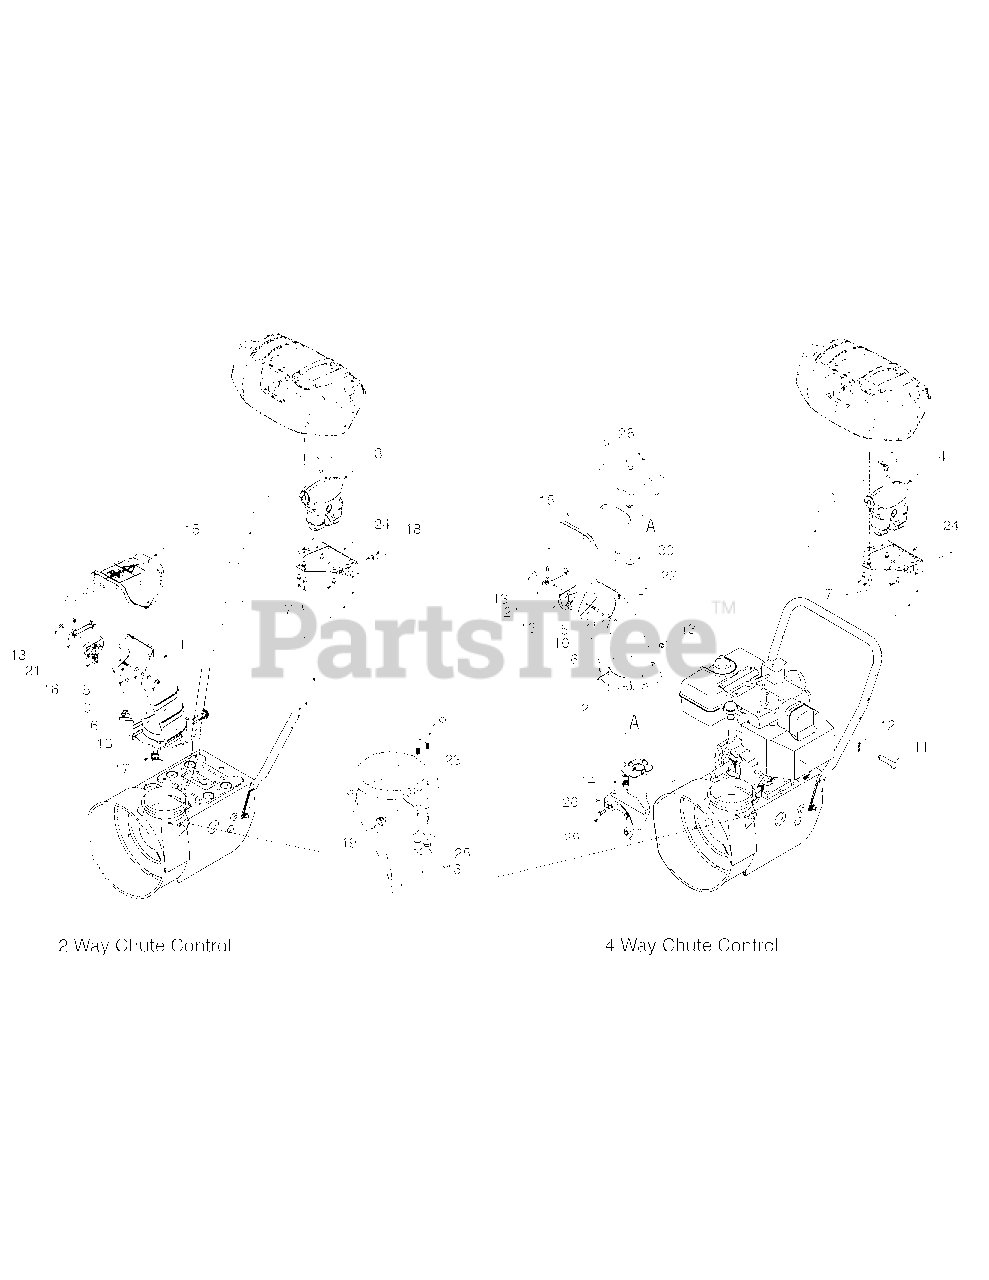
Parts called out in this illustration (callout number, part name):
2	Lower Chute (4 Way)
4	4 Way Chute Control Assembly Service Kit
5	Carriage Bolt 5/16-18 x 1.50 Gr. 2
6	Carriage Screw 5/16-18 x 1.0
7	Hi-Lo Screw 1/4-15 x .5
8	Carriage Bolt 5/16-18 x .75" Lg
9	Shoulder Screw .312 x 1.7:1/4-20
10	Hex Tapp Scr 1/4 x .75" Lg.
11	Clevis Pin 3/8 x 1.87
12	Bow Tie Cotter Pin
13	Flange Locknut 5/16-18 Gr. F Nylon
14	Wing Nut 1/4-20
15	Upper Chute w/Export Label, Remote
16	Cable Guide
17	Chute Flange Keeper
18	Shoulder Screw .25 x .50:10-24
19	Plastic Bushing .380 ID
22	Hex L-Flanged Nut 1/4-20 Gr. F Nylon
25	Flat Washer .349 ID x .879 OD x .063
26	Support Bracket
27	Hi-Lo Screw 1/4-15 x .50
28	Hex Hd. Cap Screw 1/4-20 x 1.5 Gr. 5
29	Hex Hd. Cap Screw 5/16-24 x .75
30	Flat Washer .25 ID x .63 OD x .0515
